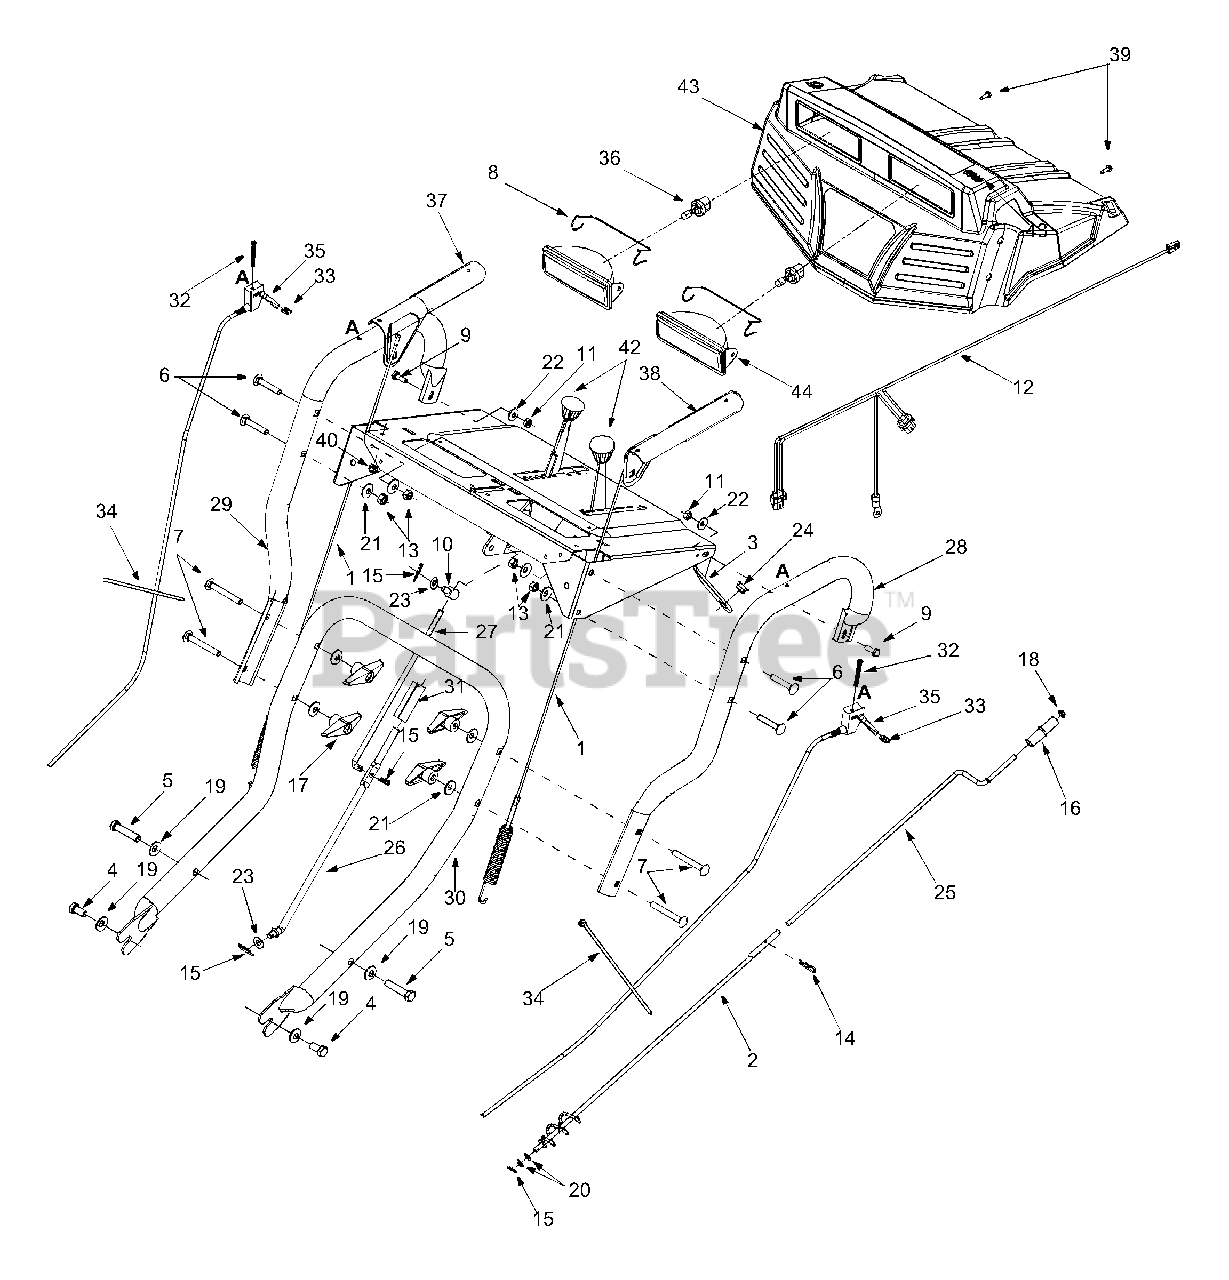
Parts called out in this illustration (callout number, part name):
1	Cable Assembly: Auger/Drive
4	Hex Screw, 3/8-16 x .88"
5	Hex Screw, 3/8-16 x 1.75"
6	Carriage Bolt 5/16-18 x 1.75"
7	Carriage Bolt 5/16-18 x 2.5"
8	Lamp Retainer
9	Hex Screw 1/4-20 x .75"
10	Ferrule
11	Hex Nut 1/4-20
12	Lamp Wire Harness
14	Hairpin Clip
15	Hairpin Clip
16	Chute Crank Knob
19	Bell Washer
20	Flat Washer
21	Beleville Washer
22	Bell Washer
23	Flat Washer
24	Plastic Bushing
26	Lower Shift Rod
27	Upper Shift Rod
31	Clutch Rod Connector
32	Oval C-Sunk Screw
33	Flat Weld Nut
34	Cable Tie
35	Trigger Control
36	Halogen Lamp
37	Handle Engagement RH
38	Handle Engagement LH
39	Special B Screw
40	Hex Sems Nut
41	Hex Lock Nut
42	Shift Knob
43	Handle Panel
44	Lens Assembly
